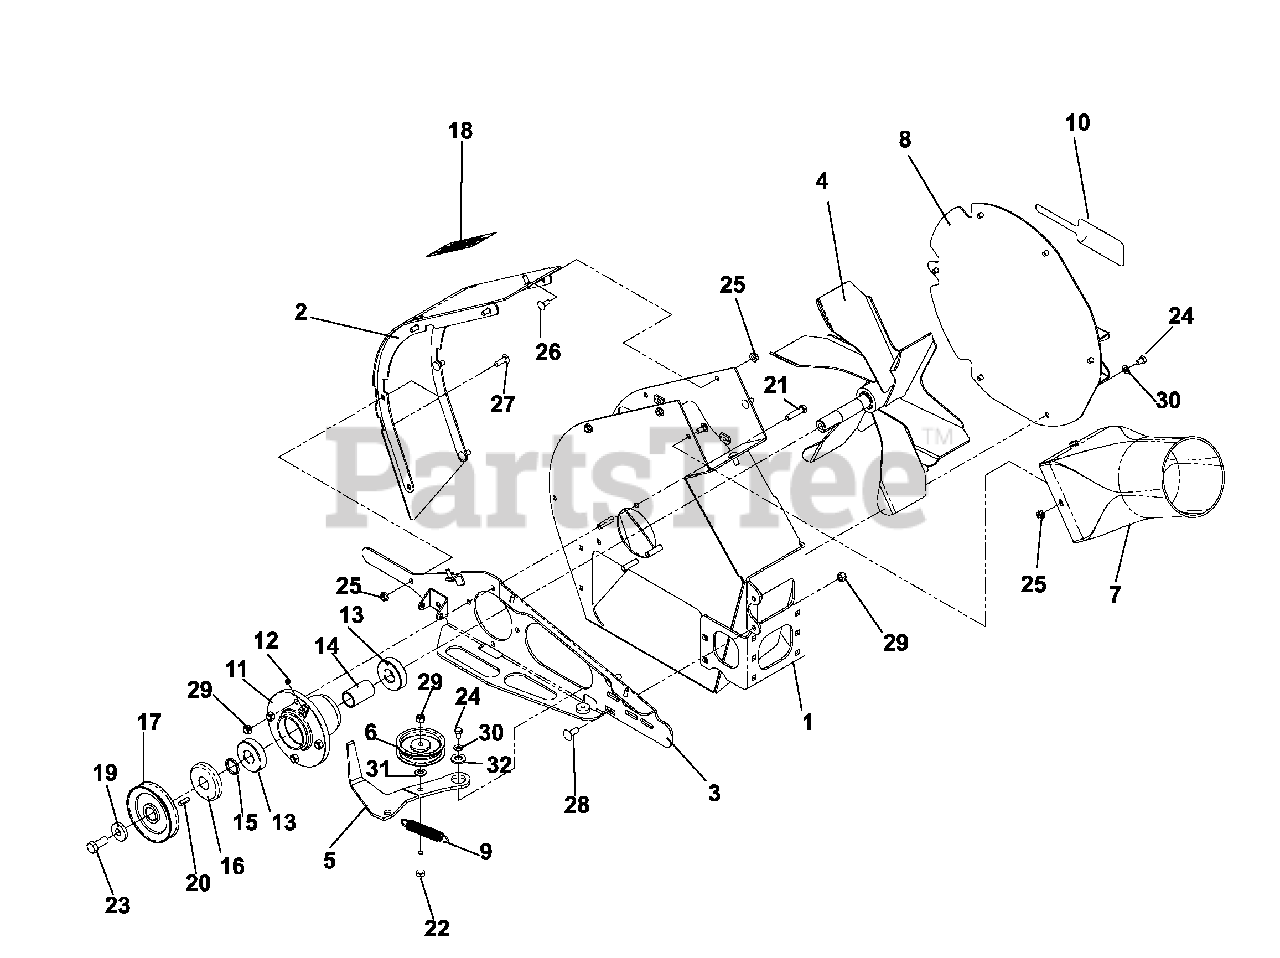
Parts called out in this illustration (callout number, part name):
1	HOUSING WLDT
2	SANDLINER WLDT.
3	HUB PLATE
4	FAN WLDT.
5	IDLER ARM
6	PULLEY, IDLER 3 METAL
7	BLOWER EXIT TUBE
8	OUTER PLT WLDT
10	DECAL, DIXON
11	DECK HUB MACHINED
12	ZERK, 3/16, DRIVE IN
13	BEARING - 6305 - 2RS
15	HUB PULLEY SPACER
16	TRASH GUARD
18	G.C.WARNING DECAL
19	WASHER .525 X 1.375 X .25
20	KEY - 1/4 X .88
21	HCS 3/8C X 1 1/2
22	HCS 3/8-16 X 1 3/4 GR5
23	1/2-20 UNF X 1 1/4 HHBLT
24	5/16-18X1/2 HHB GR5
25	5/16-18 FLANGED L-NUT
26	BOLT 5/16C X 3/4" CARRIAGE
27	RHSSNB 5/16C X 1.0
28	RHSNB 3/8C X 1
29	NUT 3/8-16 NYLOC
30	FLAT WASHER 5/16 SAE
31	WASHER 3/8 SAE FLAT
32	WASHER 1/2" FLAT
